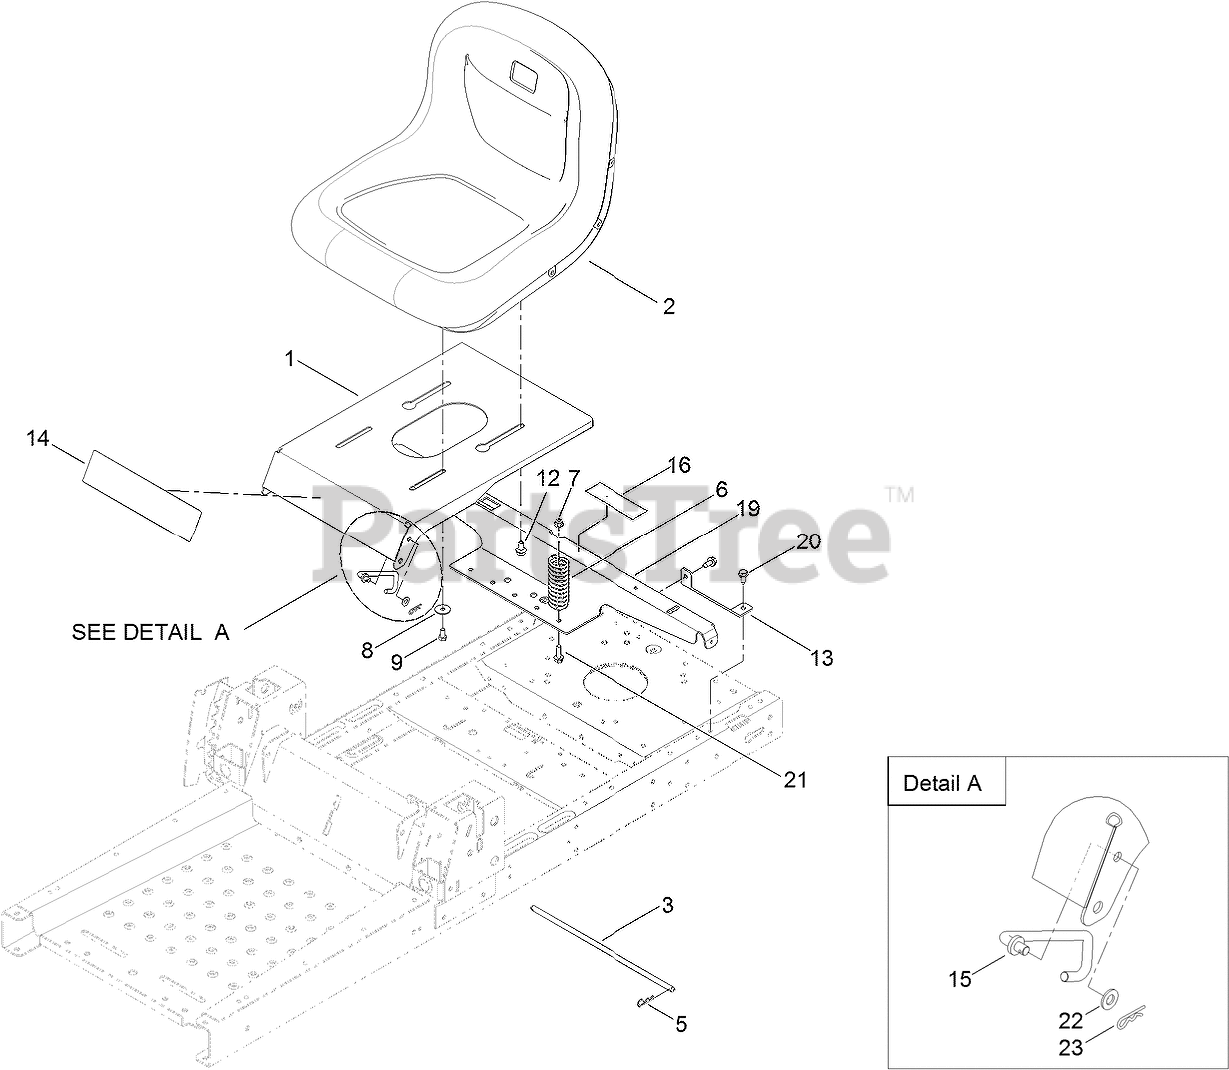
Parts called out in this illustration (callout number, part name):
1	PAN-SEAT
2	SEAT-15 INCH
3	ROD-PIVOT, NARROW
5	PIN-COTTER
6	SPRING-COMPRESSION
7	NUT-HF, NI
8	WASHER-PIVOT
9	SCREW-HH
12	BOLT-SHOULDER
13	SUPPORT-TANK, REAR
14	DECAL-TIMECUTTER
15	STOP-SEAT
16	DECAL-SERVICE, CE
19	SUPPORT-POD
20	SCREW-HWHTF
21	SCREW-HHF
22	WASHER-PLAIN
23	PIN-COTTER
